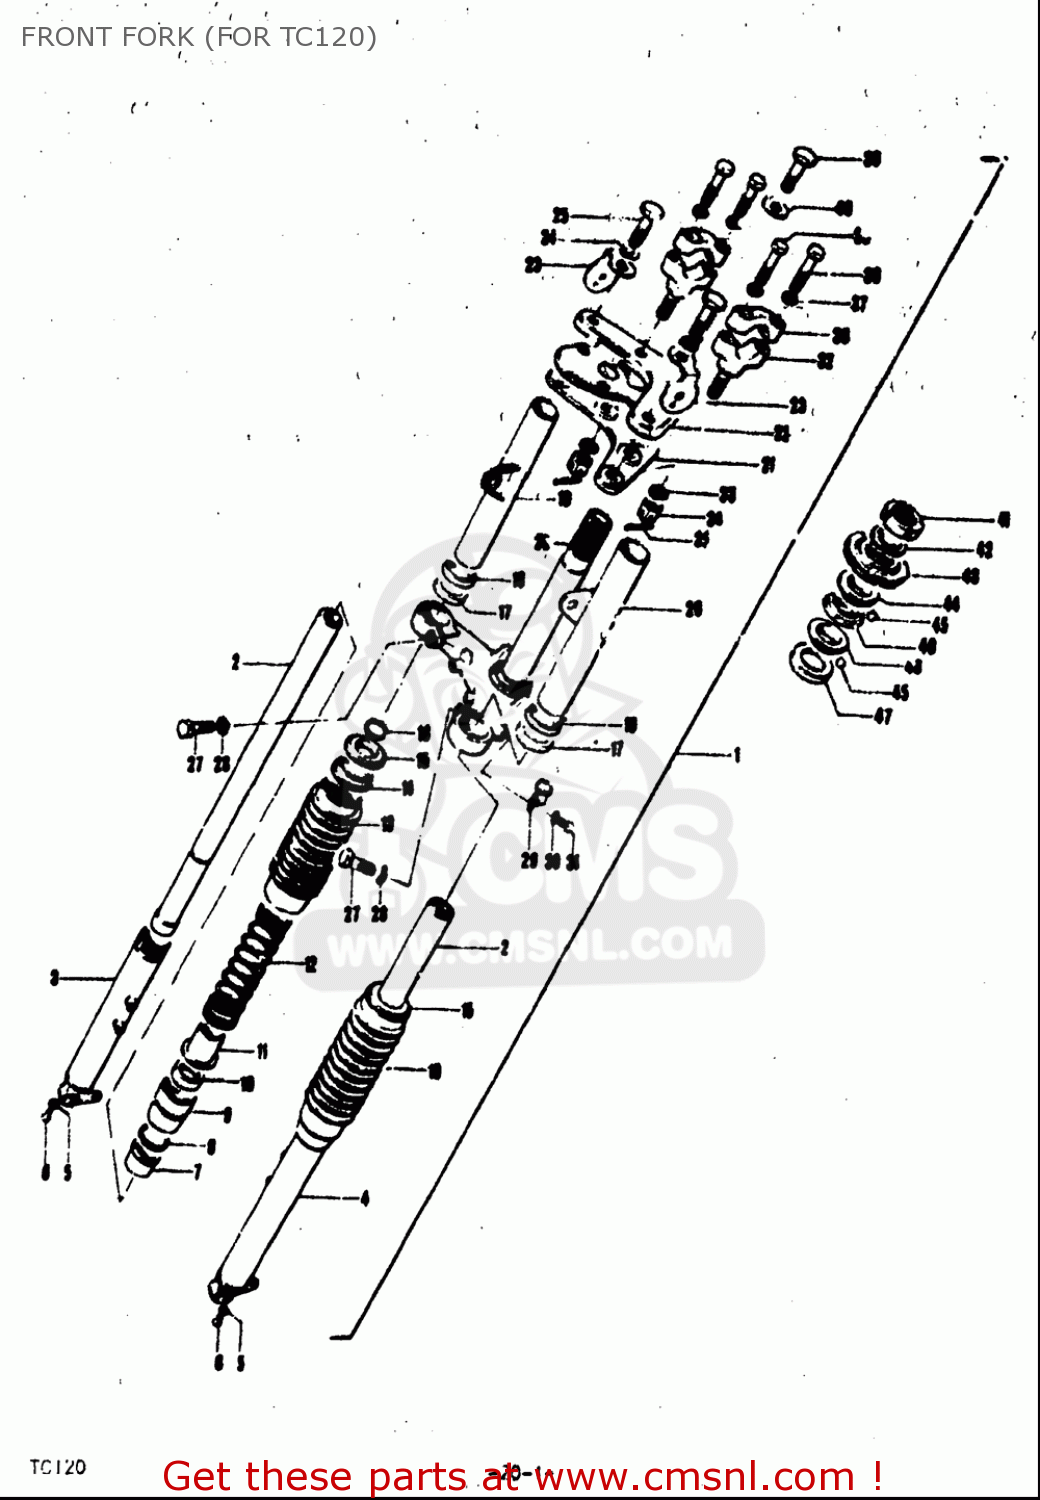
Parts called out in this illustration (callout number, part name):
5	GASKET,DRAIN,PLUG (NAS)
6	OIL DRAIN PLUG
8	O RING,OIL SEAL LWR
10	SEAL,OIL
11	DUST SEAL,FRONT FORK
18	SEAT,HEADLAMP BRACKET
24	WASHER,LOCK
25	CAP,FORK INNER TUBE
27	BOLT
28	WASHER,LOCK
29	CLIP,BRAKE CABLE
30	WASHER,LOCK
33	WASHER,LOCK
34	NUT
35	PIN
36	HOLDER,HANDLEBAR
37	WASHER,LOCK
38	BOLT
42	WASHER
43	NUT,STEERING STEM
45	BALL
